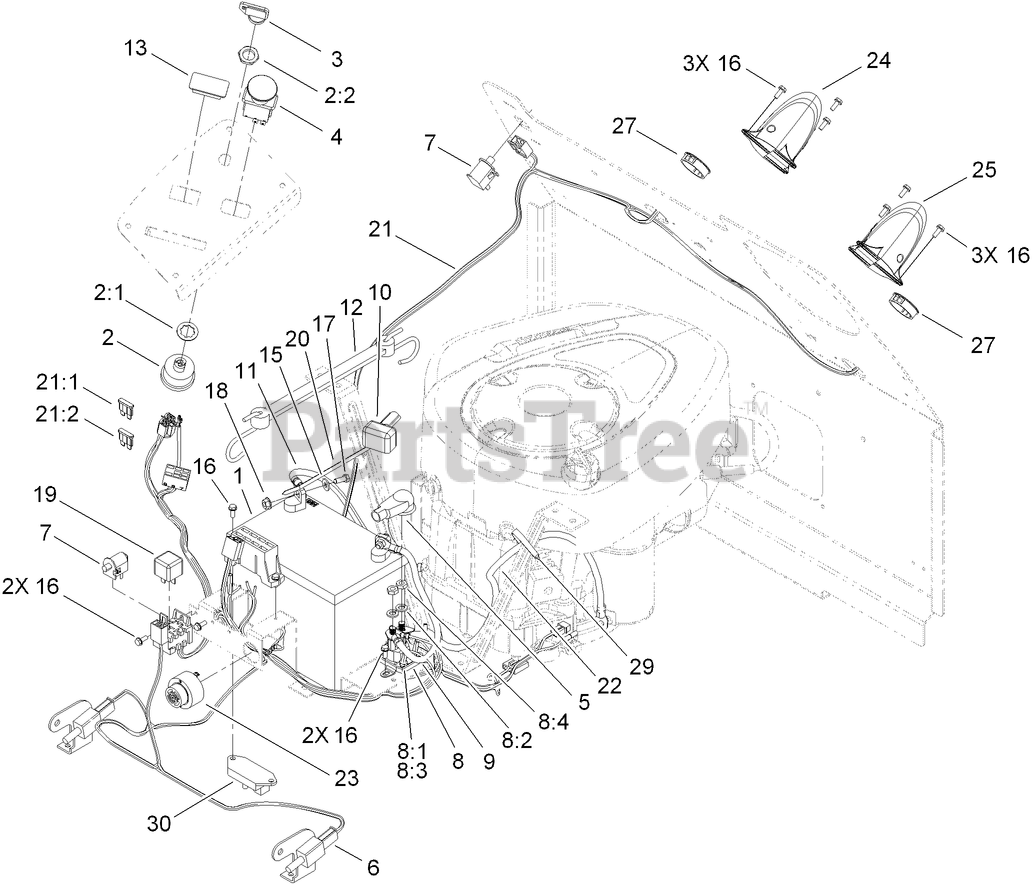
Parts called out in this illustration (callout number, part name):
2:1	WASHER-LOCK
2:2	NUT-HH
3	KEY-IGNITION
4	SWITCH-PTO,ON-ON-NONE
5	BOOT-TERMINAL
6	SWITCH
7	SWITCH-BAIL
8:1	WASHER-LOCK
8:2	WASHER-LOCK
8:3	NUT-HEX
8:4	NUT-JAM
9	CABLE-BATTERY, POSITIVE
10	BOOT-INSULATOR, TERMINAL
11	CABLE-NEGATIVE, BLACK
12	HOLDDOWN-BATTERY
13	PLUG-HOLE
15	WASHER-FLAT
16	SCREW-TAPTITE
17	SCREW-HH
18	NUT-HF
19	RELAY
20	TIE-CABLE
21	HARNESS-WIRE
21:1	FUSE-BLADE, 30 AMP
21:2	FUSE-BLADE, 25 AMP
22	WIRE-21 INCH
23	ALARM-TONE, DUAL
24	BAG SENSOR ASM
25	BAG SENSOR ASM
27	BUSHING-HARNESS, WIRE
29	CLAMP-HOSE
30	MODULE-DELAY
